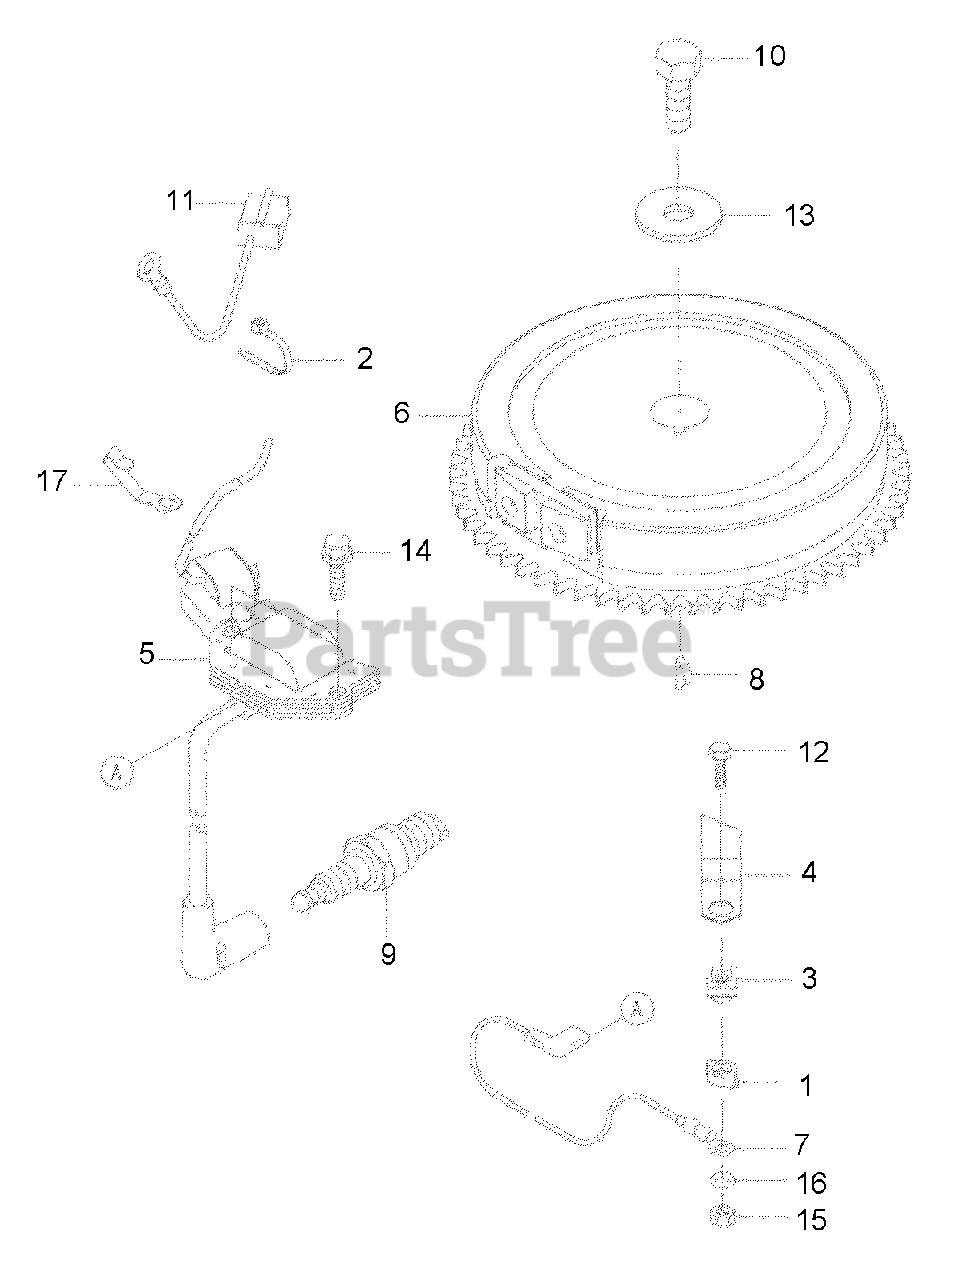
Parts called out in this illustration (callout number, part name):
5	Ignition Coil Assy.
6	Flywheel
9	Spark Plug
10	Bolt, 12x30
14	Flanged Bolt
15	Hex Nut
16	Plain Washer
